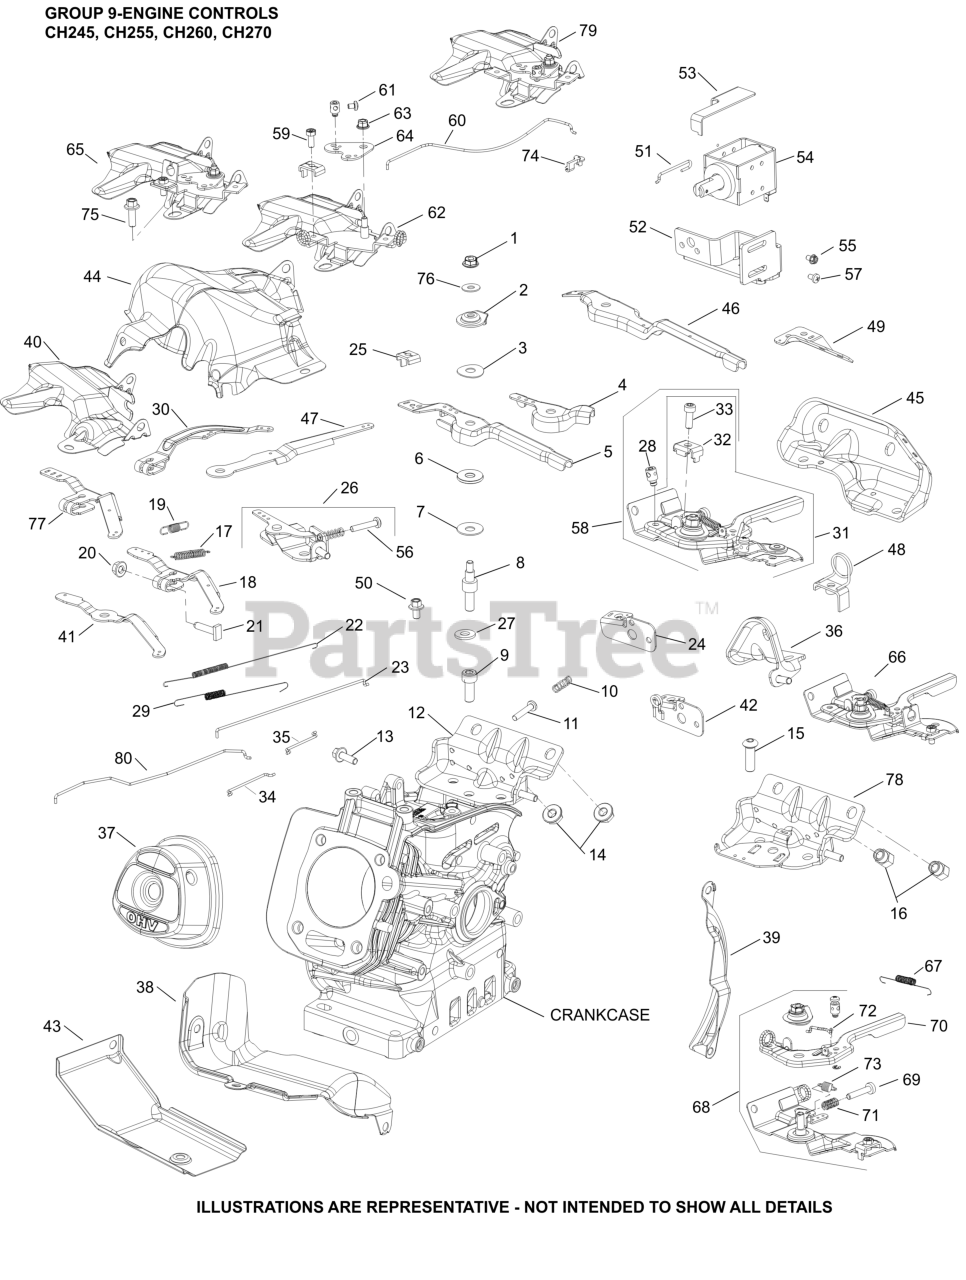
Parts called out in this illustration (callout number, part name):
10	SPRING, COMPRESSION
19	SPRING, GOVERNOR
23	LINKAGE, GOVERNOR-USE 18 079 05-S
26	CONTROL ASSEMBLY, FIXED SPEED
29	SPRING, LINKAGE
30	KIT, GOVERNOR LEVER
56	SCREW SPEED ADJUSTING
